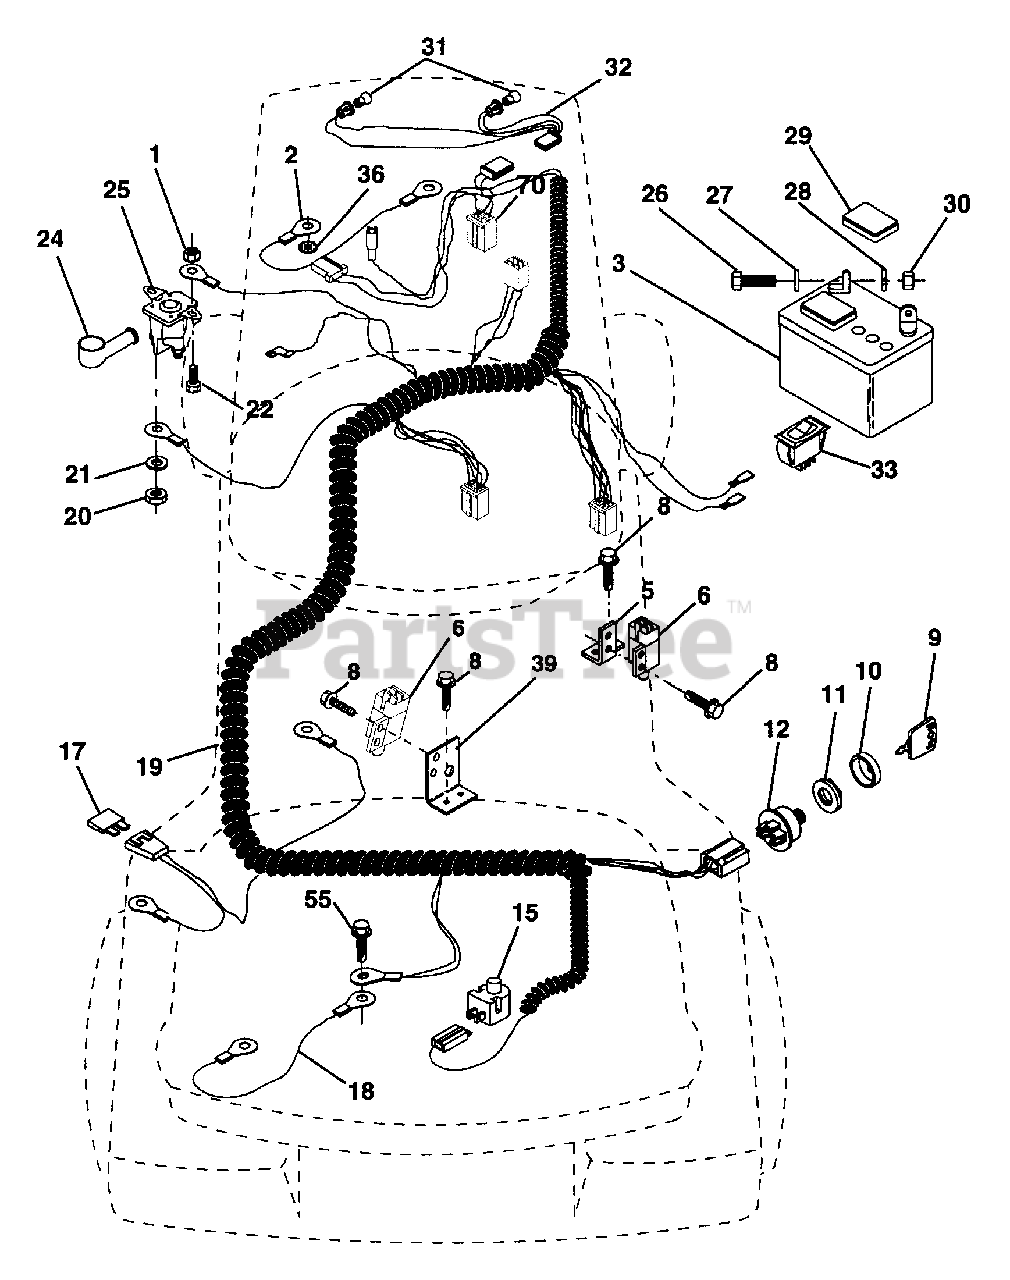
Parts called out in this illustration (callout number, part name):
1	Nut, Hex, Keps 1/4-20
2	Assembly, Cable
3	Battery
5	Bracket, Switch
6	Switch, Interlock, 4 Terminal
8	Screw, Hex Head, Self-Tapping #10-24 x 1/2
9	Key, Molded
10	Cover, Ignition Key
11	Nut, Ignition
12	Switch, Ignition
15	Switch, Plunger
18	Assembly, Cable
19	Harness, Ignition
20	Nut, Hex, Jam 1/4-20
21	Washer, Lock 1/4
22	Bolt, Hex, Fin. 1/4-20 UNC x 1/2 Grade 5
24	Cover, Terminal
25	Solenoid
26	Bolt, Hex Head 1/4-20 UNC x 3/4
27	Washer 9/32 x 5/8 x 16 Gauge
28	Washer, Lock 1/4
29	Cap, Battery
30	Nut, Hex, Fin. 1/4-20 UNC
31	Bulb, Light
32	Harness, Headlight
33	Switch, Light
36	Washer, Lock, Internal Tooth 1/4
39	Bracket, Switch Clutch
55	Screw, Thdrol 5/16-28 x 1/2
70	Harness Engine
